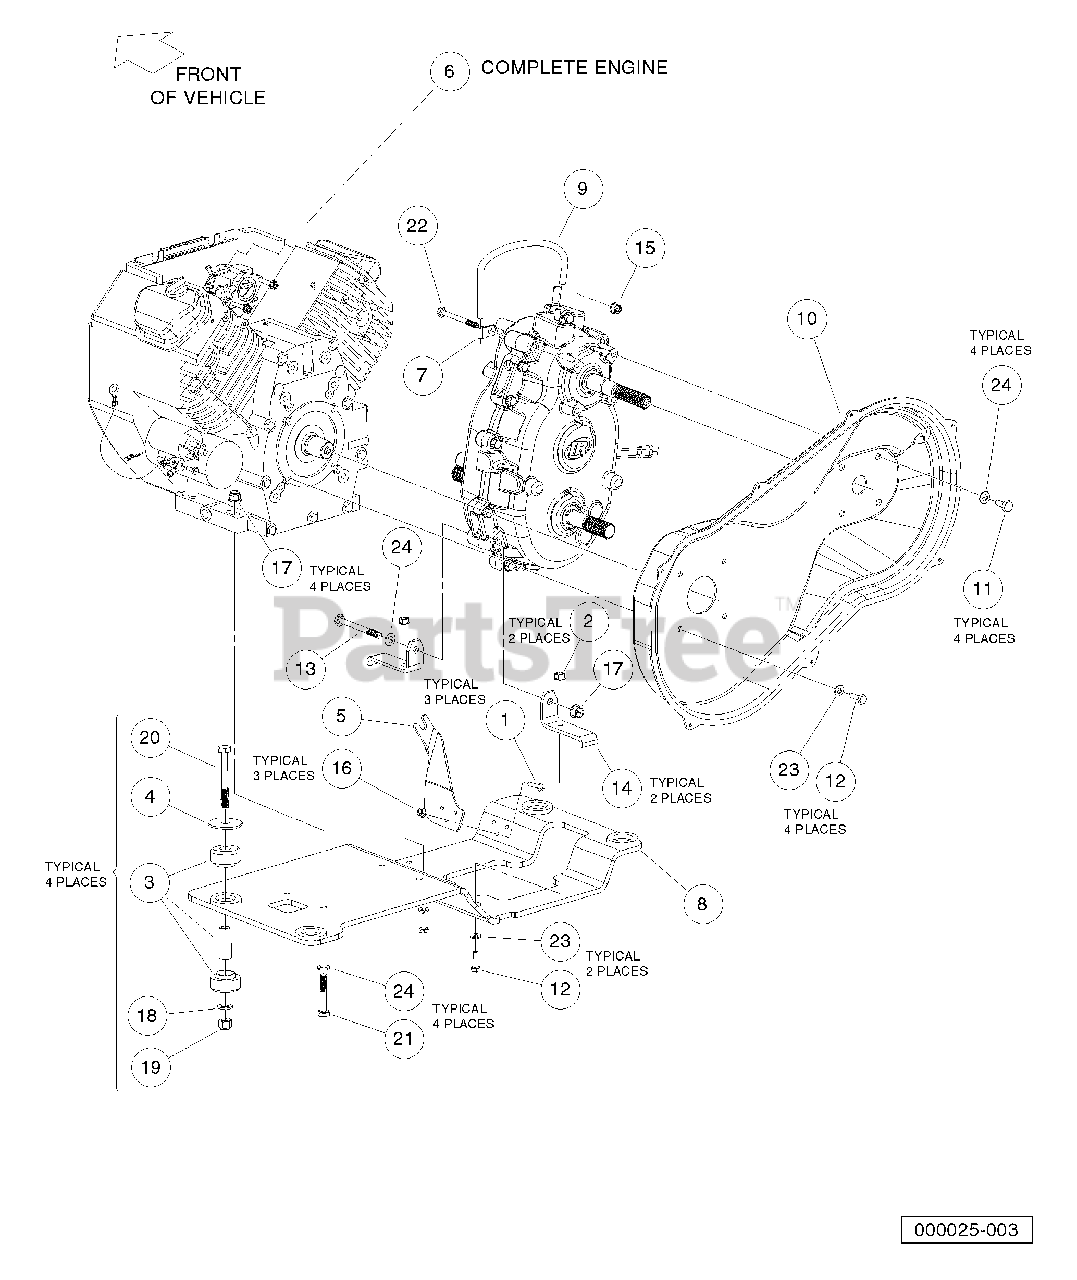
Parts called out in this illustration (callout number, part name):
1	Screw, M6-1.00 X 25mm Hex Cap
2	Nut,m8,all Metal Lock
3	Isolator Ring and Bushing
4	Washer, Snubbing, Ring N Bush
5	Bracket, FNR Trans Cable
7	P-Clamp, Insulated .312 In
8	Plate, Eng Mtg, Weld, Honda
9	Hose, Vent, Transmission
10	Cover, CVT Inner, Honda
11	Bolt, M10 X 1.5 X 20 Loctite
12	Bolt, M8 X 1.25 X 25 Loctite
13	Bolt, M10 X 1.5 X 100 Loctite
14	Bracket, Transmission Mounting
15	Lock Nut, Flg M8 X 1.25 Nylon
16	Nut Flg, M6 X 1.0 Nylon
17	Nut Flg M10 X 1.5 Nylon
18	Washer, M12 Hard
19	Locknut, M12x1.75 Nylon Insert
20	Bolt, M12 X 1.75 X 90
21	Bolt, M10 X 1.5 X 60
22	Bolt, M8 X 1.25 X 80
23	Washer, M8 Hard
24	Washer, M10 Hard
